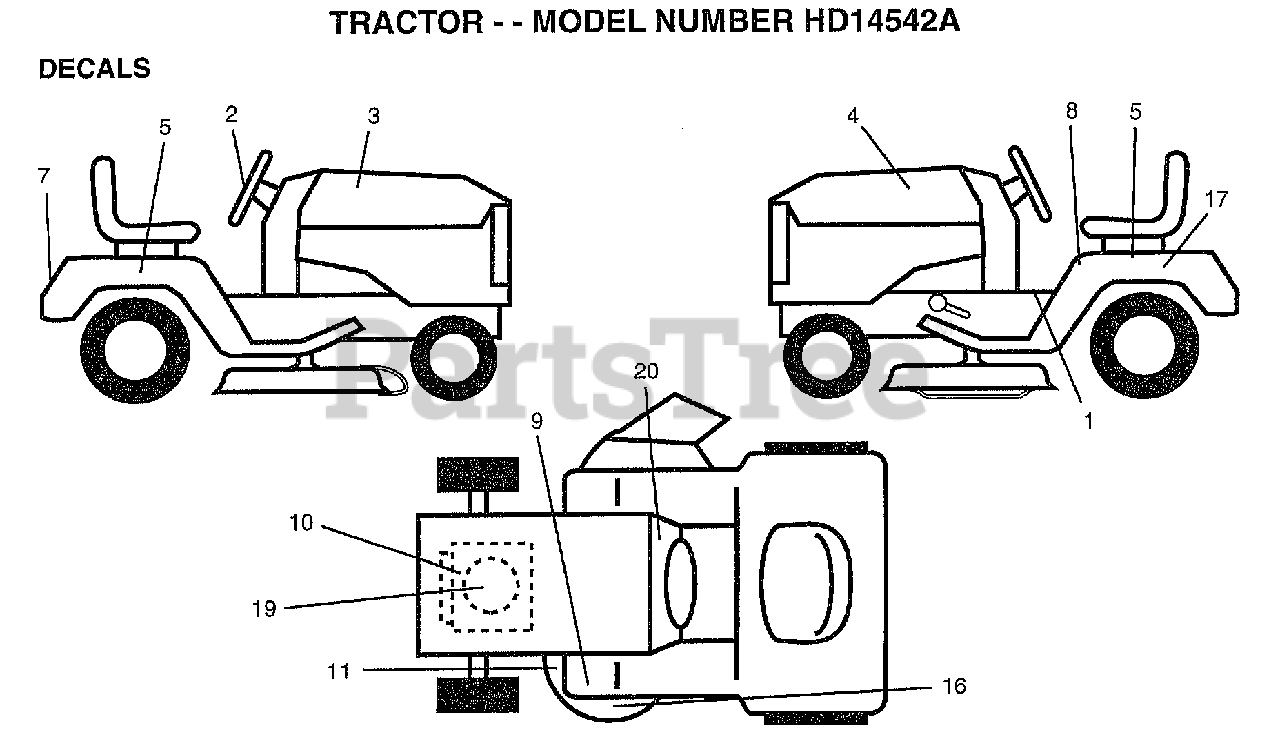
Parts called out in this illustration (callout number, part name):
2	"DECAL WHEEL,STEER"
3	DECAL HOOD RH
4	DECAL HOOD LH
5	DECAL.FENDER.SD.LAWN
7	"DECAL FENDER,LOGO"
8	"DECAL FENDER,DANG"
9	DECAL CLUT/BRAKE
10	DECAL.ENGINE
11	"DECAL-SCHEM,BELT"
16	"DECAL DECK,MULCH"
17	DECAL.BATRY.3-3908
19	DECAL.REPLACEMENT.ENG
20	DECAL DASH PNL
